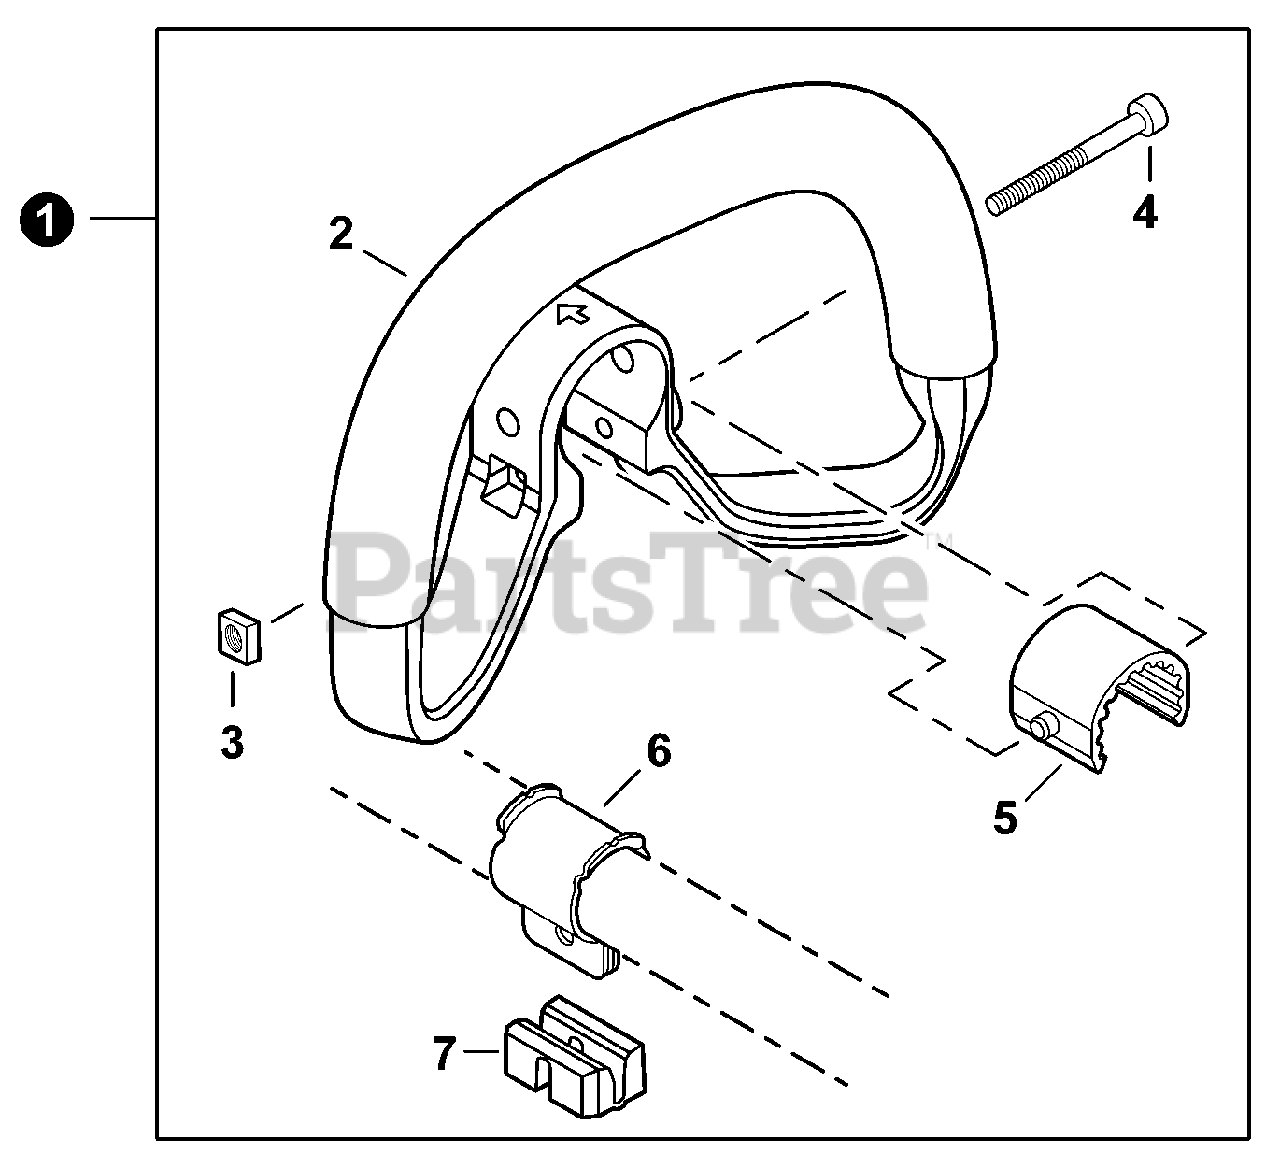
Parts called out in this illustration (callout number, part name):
1	HANDLE KIT, FRONT
2	HANDLE, SUPPORT
4	BOLT 5×45
5	CUSHION
6	BRACKET, MOUNTING
